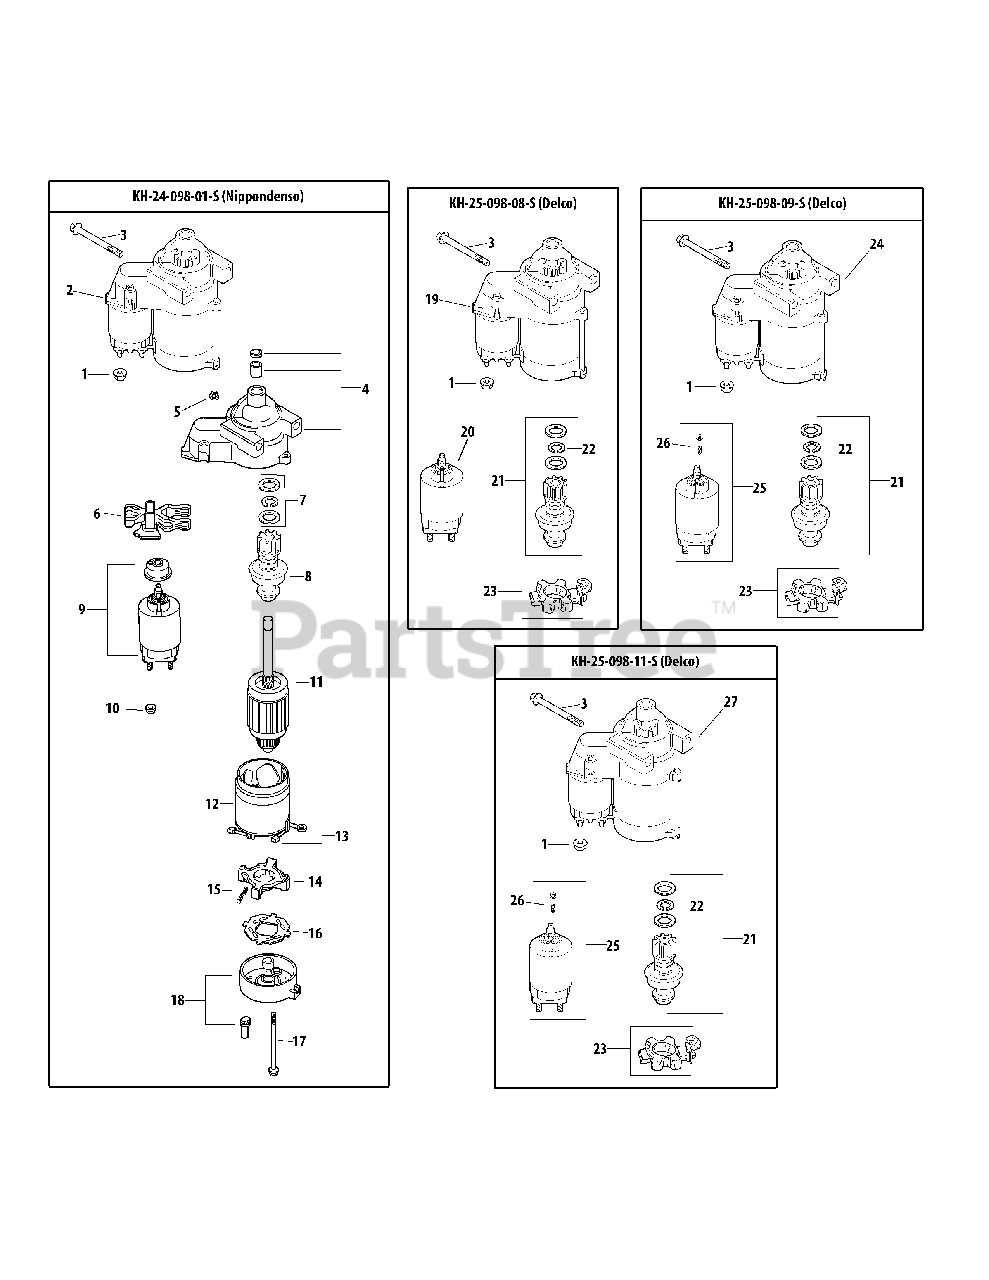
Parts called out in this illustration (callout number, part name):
1	Flange Nut, M8 x 1.25
2	Starter
4	Drive End Cap
7	Starter Repair Kit
8	Drive Pinion
12	Frame w/ Brushes (Discontinued)
13	Brush Holder
14	Brush & Spring Kit
15	Brush Spring
18	Commutator End Cap
19	Starter
21	Starter Pinion Kit (Inc. 22)
22	Retaining Ring
23	Brush Holder Kit
24	Starter
25	Solenoid Kit (Inc. 26)
26	External Torx Head Screw
27	Starter Solenoid Shift
